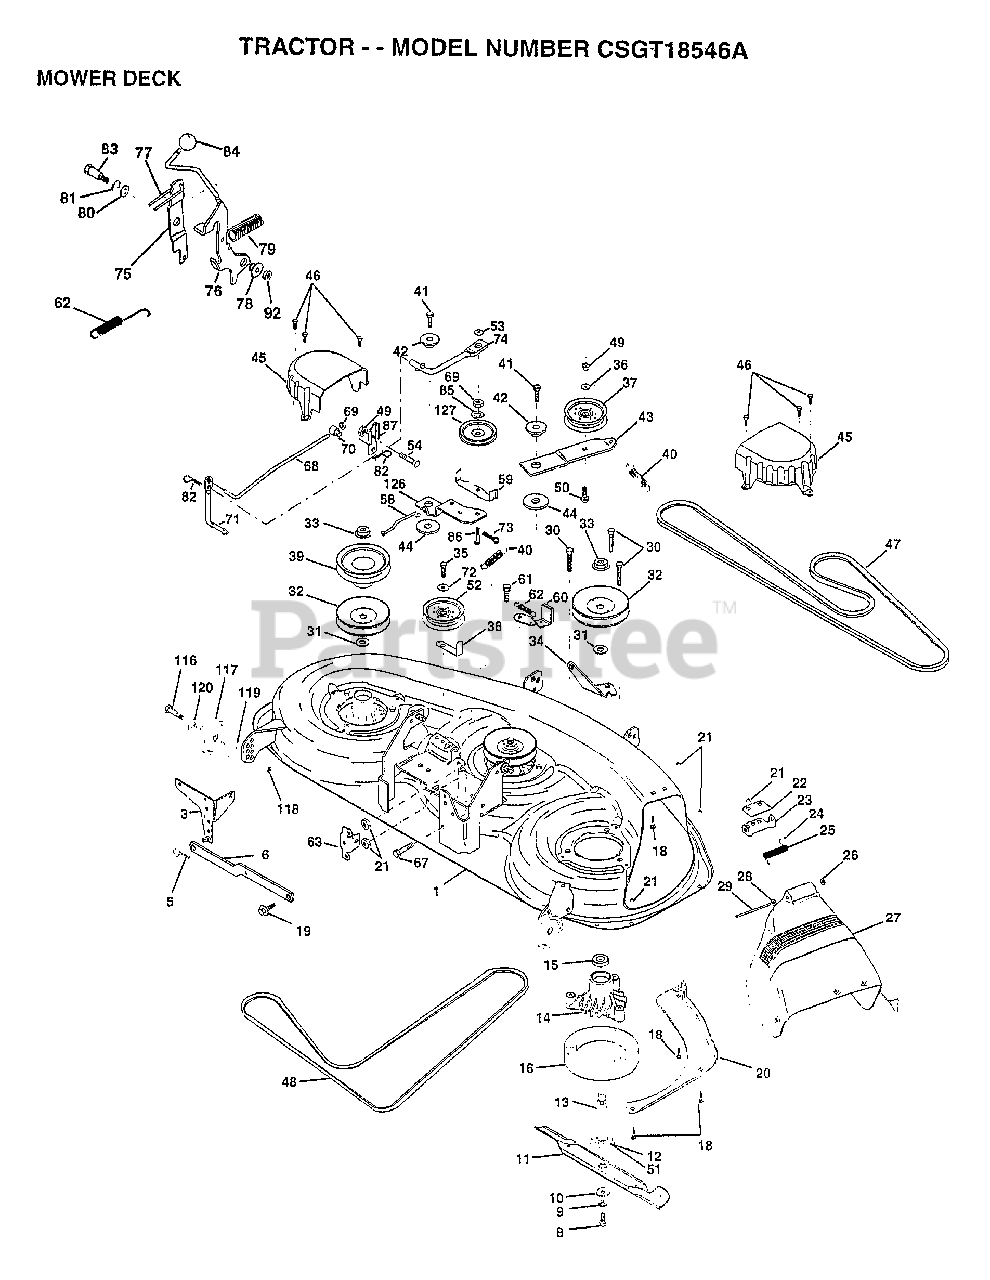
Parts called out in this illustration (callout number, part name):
1	"MOWER ASM 46"""
3	BRKT.ASM.SW.44/50
8	BLADE BOLT
10	WASHER.HARD.BLADE
12	BEARING.BALL
13	SHAFT.ASM.W/BRNG
14	HOUSING.MAND.44.V
15	BEARING
16	STRIPPER RND MWR
18	BOLT
19	BOLT SHD 5/16-18
20	BAFFFLE.VORTEX.46
22	STIFFENER BRKT
23	DEFLECTOR BRKT
24	CAP-SLEEVE LT
25	SPRING TORSION
26	NUT PUSH M
27	SHIELD DEFLECTOR
28	WASHER
29	HINGE ROD
31	WASHER
32	PULLEY.MAND.36/46
34	ANCHOR.SPRING.46
35	SCREW LT
36	WASHER
37	FLAT IDLER PULLEY
38	"KEEPER BELT,IDLER"
39	PULLEY.DRV.DCK.46
40	"SPRING.SEC.44""VEN"
41	SCREW
42	SPACER RETAINER
43	ARM.IDLER.DECK.46
44	HARDENED WASHER
45	COVER.MANDREL.46
46	SCREW.1/4-20X5/8
47	BELT-V.SEC.46.KEL
48	V BELT MOWER
50	BOLT.3/8-16X1.50
51	WASHER.FELT.
52	"PULLEY IDLER,FLAT"
53	WASHER
54	BOLT
58	"LINK BRAKE, 43"""
59	"GUIDE BELT,46""MOW"
60	ARM ASM BRAKE
61	BOLT.SHLD.5/16-18
62	RETURN SPRING
63	"BRKT ROD,CLUTCH"
67	BOLT
69	NUT
70	TRUNION ADJ
71	PIVOT ROD
72	WASHER HYT
73	COTTER PIN
74	LINK CLUTCH
75	CLUTCH ARM SECOND
76	LEVER ASM-CLUTCH
77	SPRING KEEPER
78	BUSHING
79	SPRING.CLUTCH.MWR
80	WASHER
81	RING
82	RETAINER M
83	SHOULDER BOLT
84	KNOB T(3/8 HOLE)
85	LOCKWASHER
86	"BOLT CARR, SH"
87	BRACKET.EXTENSION
92	NUT
116	BOLT M
117	WHEEL.GAGE.BLK.PL
118	LOCKNUT
119	WASHER
120	WASHER
127	PULLEY.IDLER.4.25
